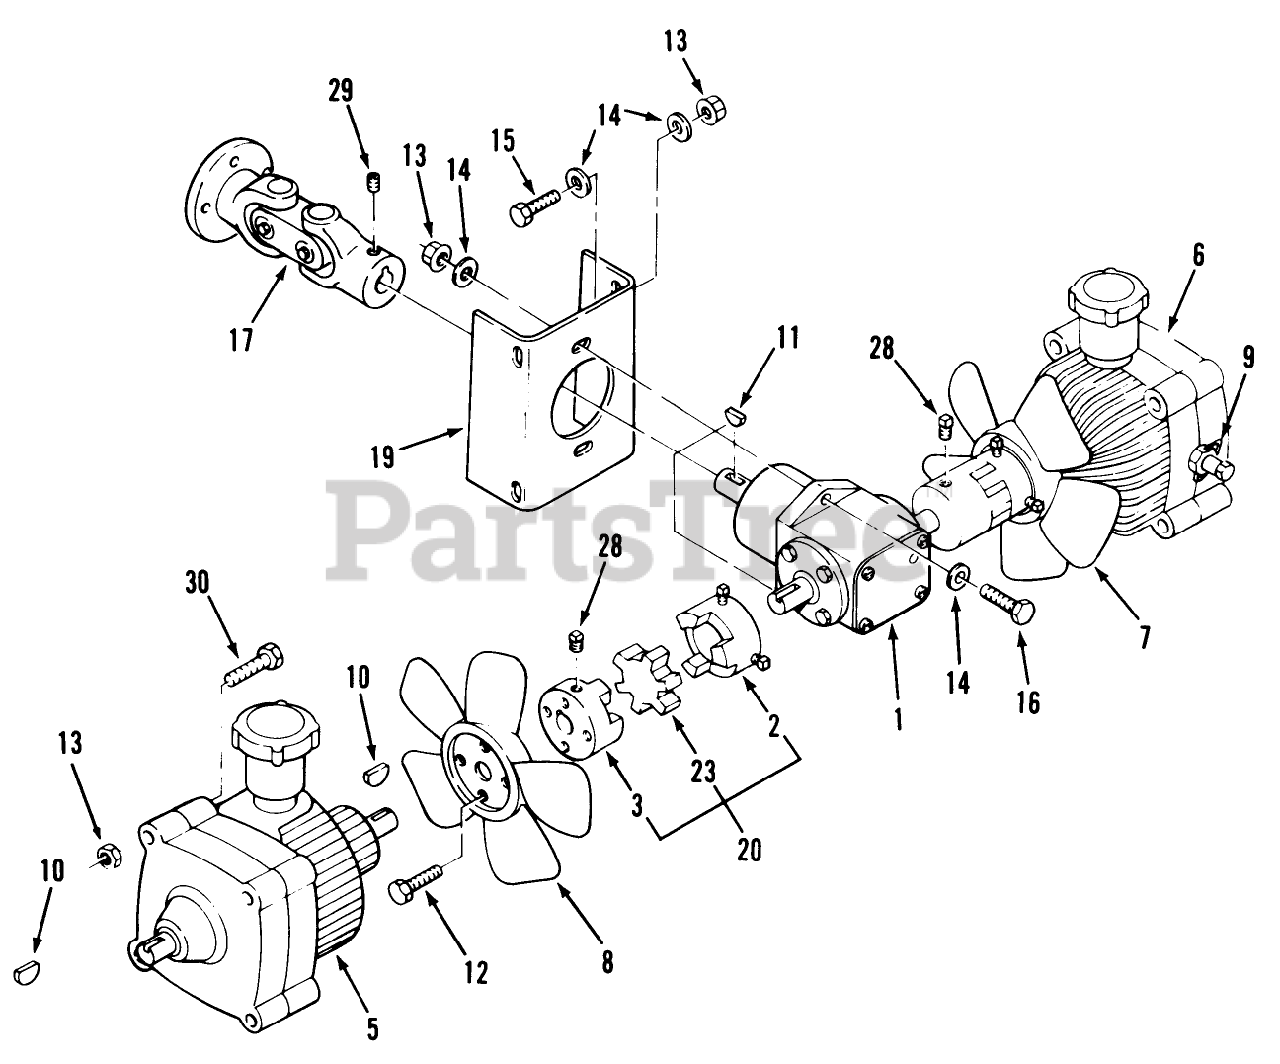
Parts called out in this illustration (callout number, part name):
1	GEAR BOX-T
2	COUPLING-KEYED
3	COUPLING-KEYED
5	TRANS-HYDRO CCW.
6	TRANS-HYDRO CW
7	Fan-LH, Clockwise
8	BLADE-FAN R.H.
9	CLIP-DUMP VALVE
10	KEY-HIPRO
11	KEY-HI-PRO
12	Screw
13	NUT
14	Washer
15	BOLT
16	Bolt
17	U-JOINT ASSY W/FLANGE
19	BRACKET-GEAR BOX B
20	Coupler Complete (Includes 2, 3 & 23)
23	SPIDER-COUPLING
28	Screw-Sq. Hd. Set
29	Setscrew 3/8-16 x 1/2
30	Screw-Hex. Hd.
